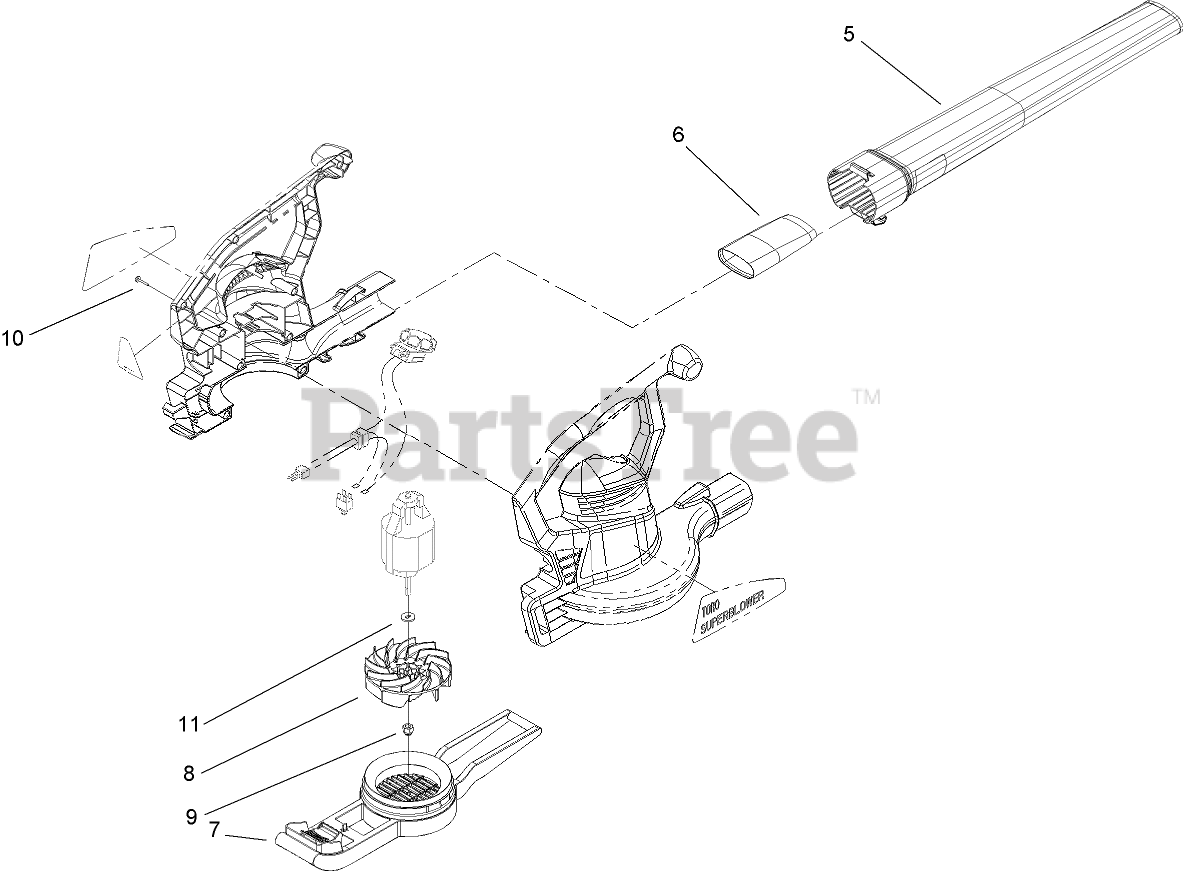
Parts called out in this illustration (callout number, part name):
5	TUBE-BLOWER
6	TUBE-INSERT
7	COVER-INLET
8	IMPELLER-BLOWER
9	NUT-IMPELLER
10	SCREW-PPH
11	WASHER
